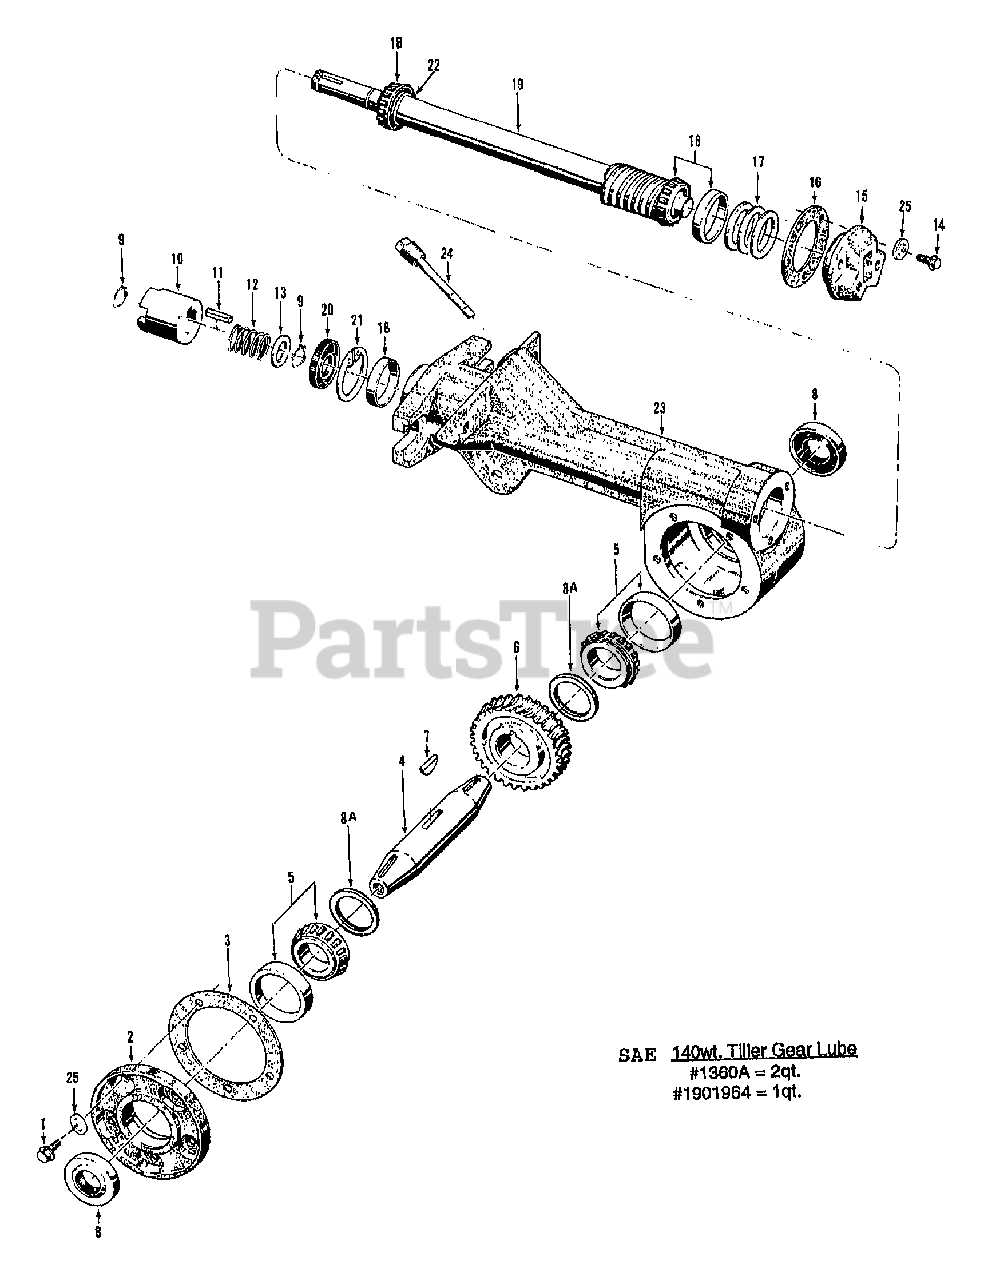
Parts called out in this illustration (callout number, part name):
1	SCR-HXSKT 1/4-20X.625
2	COVER-W/SCRS(TLR) (9780) (REF.#1)
3	GASKET-TILLER COVER
4	SHAFT-TILLER
5	KIT-BEARING CUP & CONE
6	GEAR-WORM MACH
7	KEY-WOODRUFF .250X1.01
8	SEAL-OIL TILLERSHAFT
8A	WASHER-1.75X1.260X.054
9	RING-RETAIN EXT .707 ID
10	KIT-CLUTCH DOGS TILLER
11	KEY-.188 SQX1.0
12	SPRING (TC)
13	SHIM-1.0X.7656X.062
14	SCR-HFLK 1/4-20X.87
15	CAP-REAR #1115
16	GASKET-BRG COVER
17	SHIM-1.75X1.5X.01
17	SHIM-1.75X1.5X.03
17	SHIM-1.75X1.5X.005
17	SHIM-1.75X1.5X.062
18	KIT-BRG CONE&RACE-DRIVESHAFT
19	KIT-TILLER DR SHAFT
20	SEAL-OIL DRIVESHAFT
21	RING-RETAINING 5000-181
22	SHIM-1.0X.7656X.062
23	HSG-TLR ATT W/SLEEVE/RACEH3 (REF.#5)
24	ASSM-OIL DIPSTICK
24	ASSM-DIPSTICK HORSE TRANS
25	WASHER
